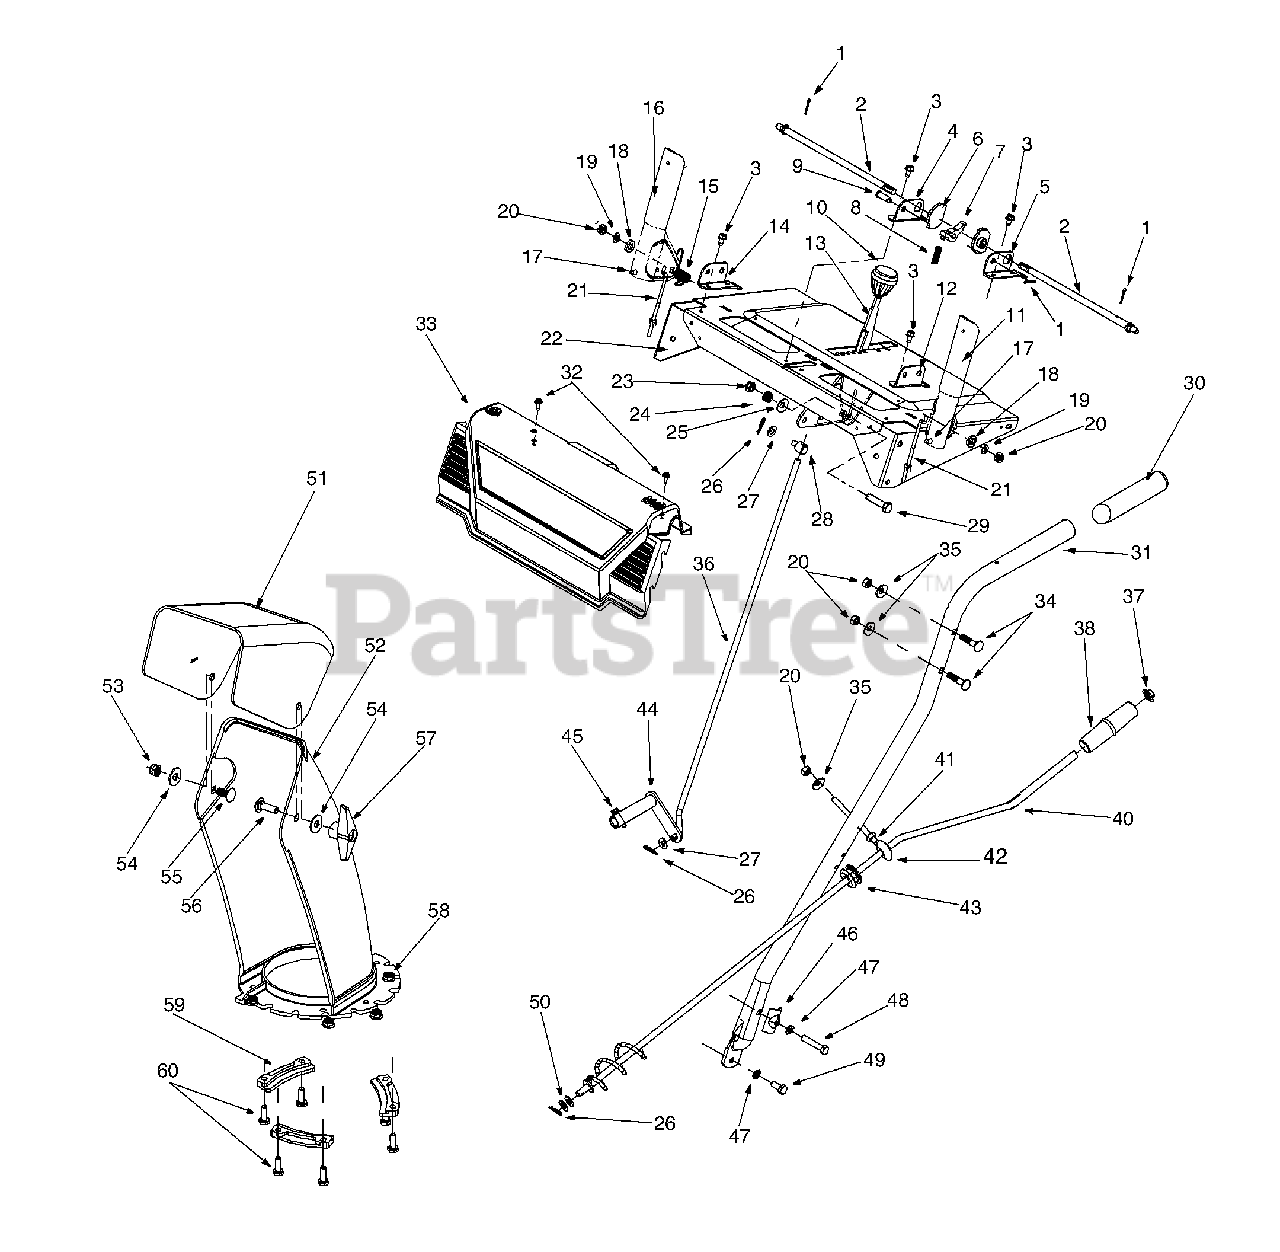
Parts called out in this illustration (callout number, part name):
1	Cotter Pin
3	Hex Washer Screw 1/4-20 x .5
6	Cam Lock Handle
7	Handle Lock Pawl
8	Compression Spring
9	Clevis Pin
10	Knob
11	Handle Assy--LH
15	Torsion Spring
16	Handle Assy--RH
17	Rubber Bumper
18	Washer
19	Lock Washer 5/16
20	Hex Nut 5/16-18
21	"Z" Fittings For Control Cables
24	Compression Spring
25	Bell Washer
26	Cotter Pin
27	Flat Washer 5/16
28	Ferrule
29	Hex Cap Screw 3/8-24 x 1.50
33	Handle Panel
34	Carriage Bolt 5/16-18 x 1.50
35	Bell Washer .340 ID x .872 OD
36	Shift Rod
37	Push Cap
38	Chute Directional Control Knob
40	Chute Directional Control Assembly
41	Hex Nut 5/16 - 18
42	Chute Directional Control Eyebolt
43	Rubber Grommet
45	Hex Washer Screw 1/4-20 x 1.0
46	Handle Tab
47	Lock Washer 5/16
48	Hex Cap Screw 5/16-18 x 1.75
49	Hex Cap Screw 5/16-18 x .75
50	Flat Washer
51	Upper Chute
52	Lower Chute
53	Hex Lock Nut 5/16-18
54	5/16 Washer
55	Carriage Bolt 5/16-18 x .75
56	Carriage Screw 5/16-18 x 1.0
58	Hex Lock Nut 1/4-20
59	Flange Keeper
60	Hex Cap Screw 1/4-20 x .75
